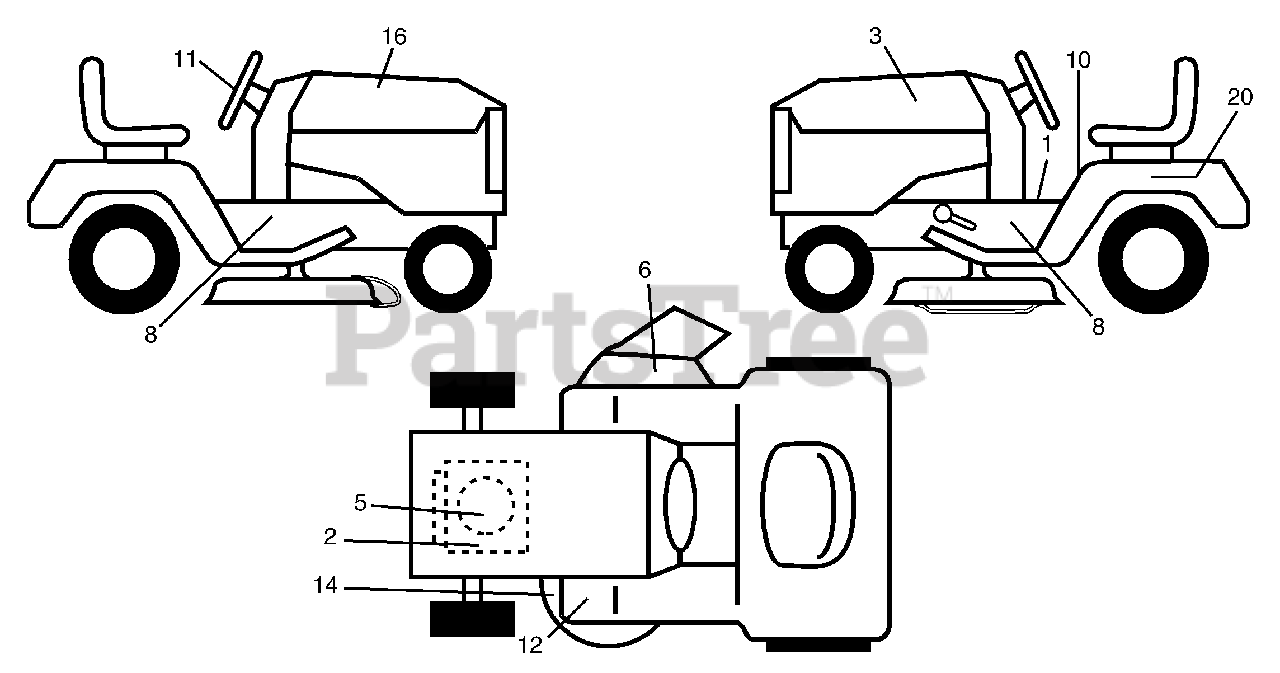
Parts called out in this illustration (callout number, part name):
1	Decal Oper
2	Decal Tec 3 Yr Warranty
3	Decal Hood LH
5	Decal HP Engine
6	Decal Deck "B" 42"
8	Decal Chassis
10	Decal Fender Danger
11	Decal Ins Strg Whl
12	Decal Footrest
14	Decal V-Belt Schematic
16	Decal Hood Rh
20	Decal Bat Dan/Psn
